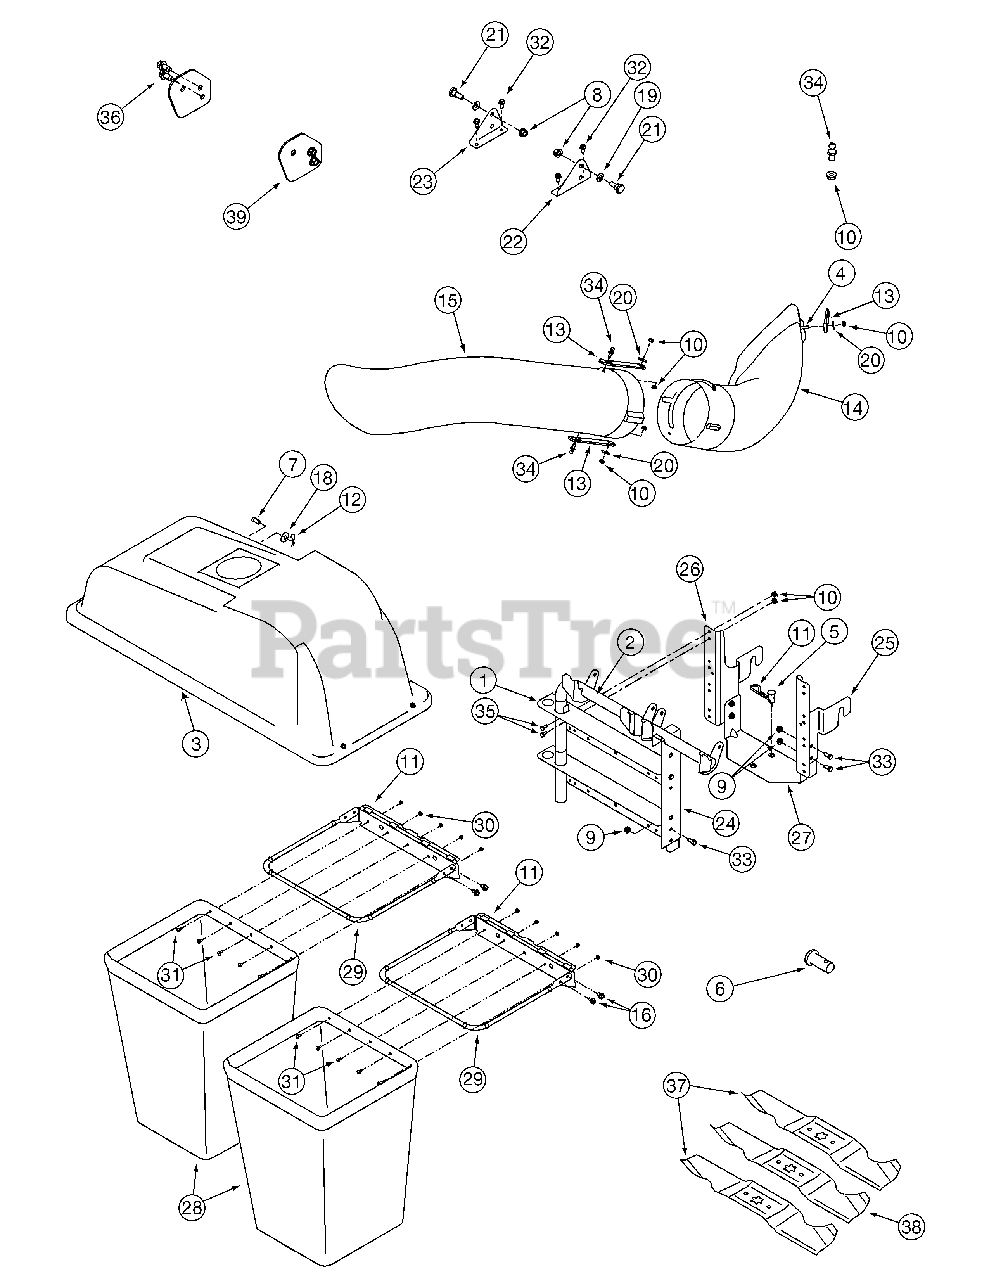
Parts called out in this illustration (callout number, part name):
3	Grass catcher Cover Assembly
4	Screw 1/4-20 x 1"
5	Clevis Pin
6	Clevis Pin (on older model tractors)
7	Clevis Pin
8	Lock Nut 7/16-20
9	Lock Nut 5/16-18
10	Hex Flange Lock Nut, 1/4-20
11	Hairpin Clip
12	Click Pin
13	Chute Strap
14	Discharge Chute 46"
15	Catcher Tube
16	Self-Tapping Screw 5/16-18
18	Bell Washer
19	Bell Washer
20	Flat Washer
21	Shoulder Screw
22	Support Bracket (RH)
23	Support Bracket (LH)
28	Catcher Bag
30	Hex Sems Nut, #10-24
31	Machine Screw, , #10-24 x .5
32	AB Screw 5/16-12
33	Hex Screw 5/16-18 x 0.75"
34	Grass catcher Pin
35	Hex Screw 1/4-20 x0.620
36	Self-tapping Screw 3/8-16 x 0.75"
37	Blade 16.28" Lg.
38	Blade 14.88" Lg.
